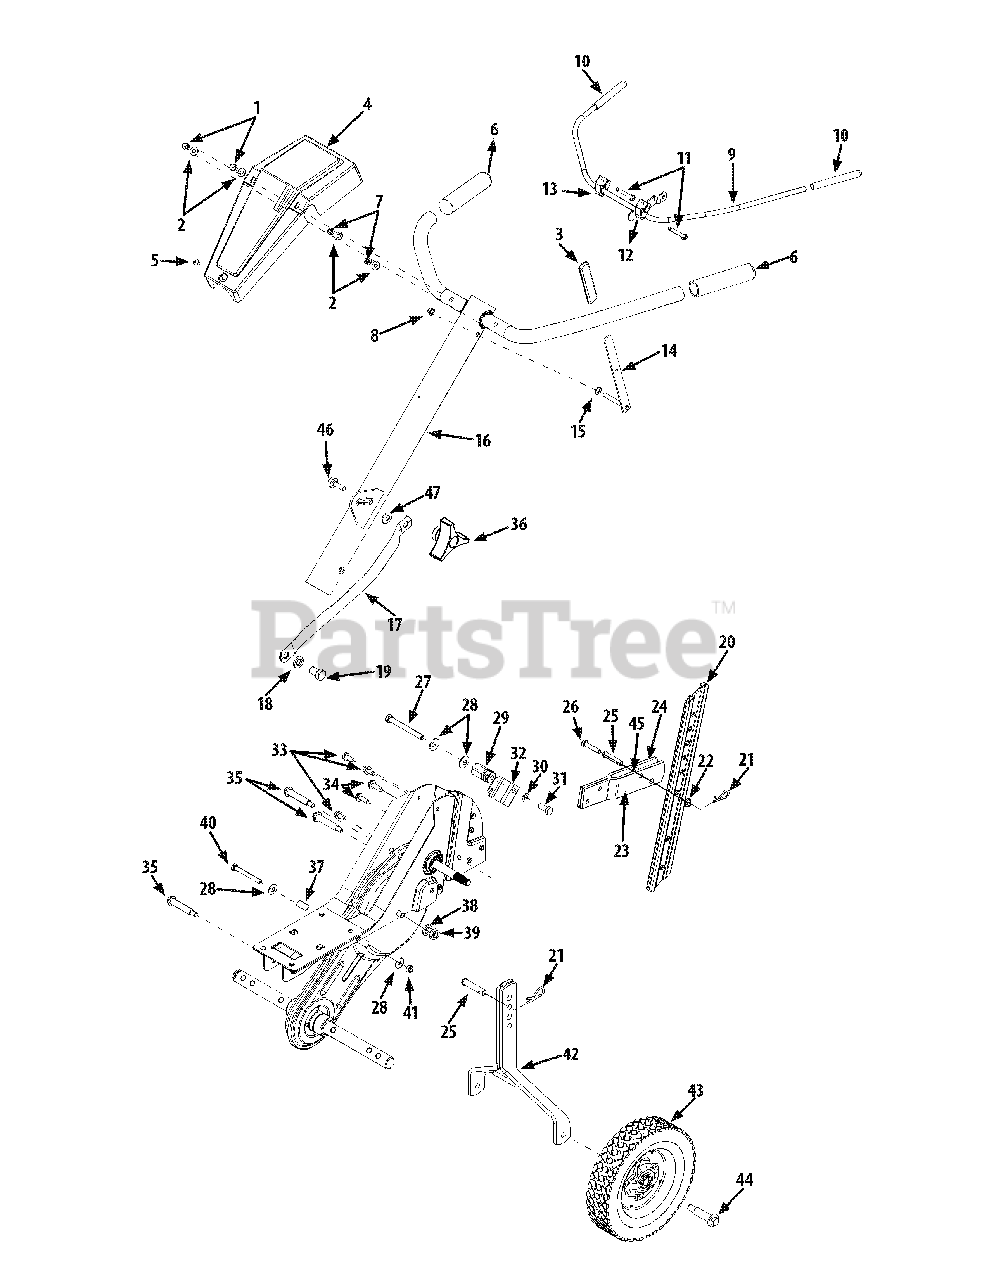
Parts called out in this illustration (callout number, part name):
1	Acorn Lock Nut, 1/4-20
2	Flat Washer, .271" x.630"
3	Reverse Handle Grip
4	Handle Cover w/o throttle
5	Truss Machine Screw, #10 x 1/2"
6	Handle Grip
7	Hex Nut, 1/4-20
8	Cap Speed Nut
9	Clutch Handle Assembly
10	Clutch Grip
11	Hex Bolt, 1/4-20 x 2.25"
12	Clutch Handle Holder
13	Flat Washer, .385" x .62"
14	Reverse Handle Assembly
15	Flat Washer, .344" x .62"
16	Handle Assembly Complete
17	Handle Brace
18	Lock Washer, 1/2
19	Hex Bolt, 1/2-20
20	Depth Bar
21	Cotter Pin
22	Hex Flange L-Nut, 5/16-18
23	Tail Piece Bracket, Left
24	Tail Piece Bracket, Right
25	Clevis Pin
26	Hex Bolt, 5/16-18 x 1.5"
27	Hex Bolt, 5/16-18 x 3"
28	Bell Washer, .340" x .872"
29	Hex Nut
30	L-Washer, 5/16"
31	Hex Bolt, 5/16-18
32	Cable Guide Bracket
33	Hex Washer Screw, 5/16-18 x .62"
34	Hex Washer TT-Tap Screw
35	Shoulder Bolt, 5/16-18
36	Hand Knob
37	Spacer
38	Lock Washer,7/16
39	Jam Nut, 7/16-20
40	Hex Bolt, 5/16-18 x 2.75"
41	Nylon Hex Nut, 5/16-18
42	Wheel Hanger Bracket Assembly
43	Wheel, 8 x 1.75
44	Shoulder Screw, .496 x 1.445
45	Spacer
46	Carriage Bolt, 5/16-18 x 1
47	Bell Washer, .34"
